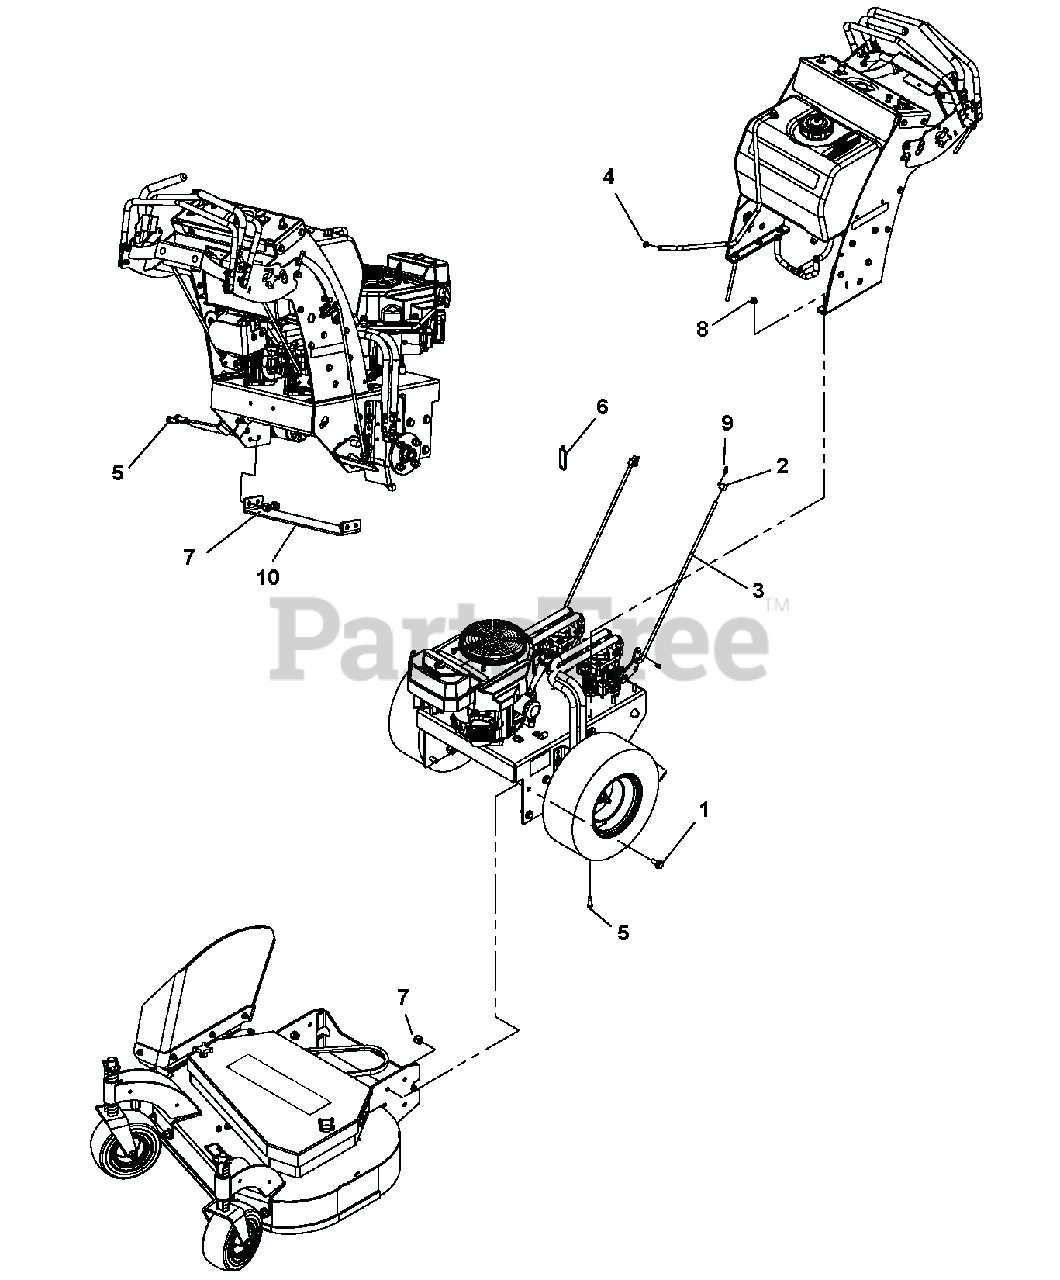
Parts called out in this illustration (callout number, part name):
1	BOLT, 1/2-13X1.25 SFH Y
2	SWIVEL, 3/8-24
3	ROD, DRIVE CONTROL G2FW
4	CLAMP, FUEL LINE
5	BLT-HEX .38-16X1.25 GR5 YWZC
6	CABLE TIE, .15 X 8.50
7	LOCKNUT, 1/2-13 NYLOC Y
8	NUT-LK-NYL-FLG .38-16 YWZC
9	RING, RUE .375 X .054 X 1.254
10	PLATE, ENGINE BED REAR SCAMPER
